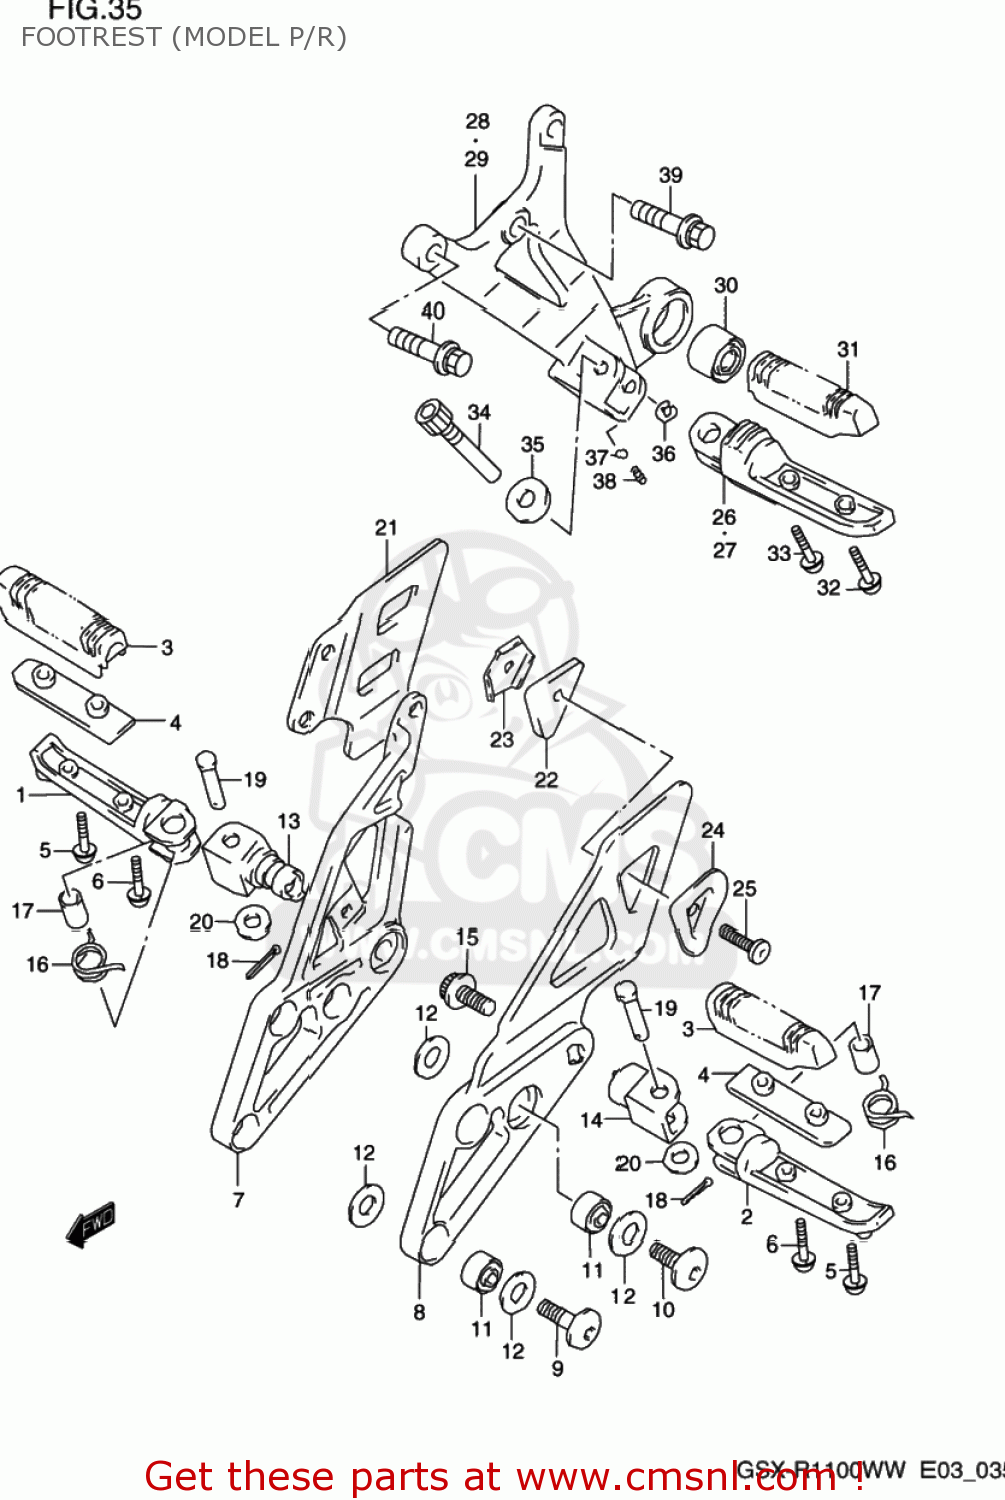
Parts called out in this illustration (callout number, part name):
1	BAR,FOOTREST,R
2	BAR,FOOTREST,L
3	RUBBER,FOOTREST
4	BAR,FR FOOTREST NO.2
5	SCREW
6	SCREW
7	BRACKET,FOOTREST,R
8	BRACKET,FOOTREST,LEFT
9	BOLT L:30
10	BOLT(8X25)
11	BUSH(12X20X16)
12	WASHER(12.6X24X1.9)
13	HOLDER,FOOTREST
14	HOLDER,FOOTREST,LEFT
15	BOLT(10X24)
16	SPRING
17	SPACER(8.1X12X22)
18	PIN 20X15
19	PIN
20	WASHER(8.5X18X1)
21	GUARD,FR FOOTREST,R
22	WEIGHT,FOOTREST BRACKET,L
23	COVER,FOOTREST WEIGHT
24	PLATE,REINFORCEMENT,L
25	SCREW(6X20)
26	BAR,PILLION FOOTREST,R
27	BAR,PILLION FOOTREST,L
28	BRACKET COMP,PILLION FOOT
29	BRACKET,PILLION FOOTREST,L
30	BUSHING 10X28.1X19
31	RUBBER,FOOTREST
32	SCREW
33	SCREW
34	BOLT,PILLION FOOTREST
35	WASHER
36	E.RING
37	BALL
38	SPRING
39	BOLT
40	BOLT
